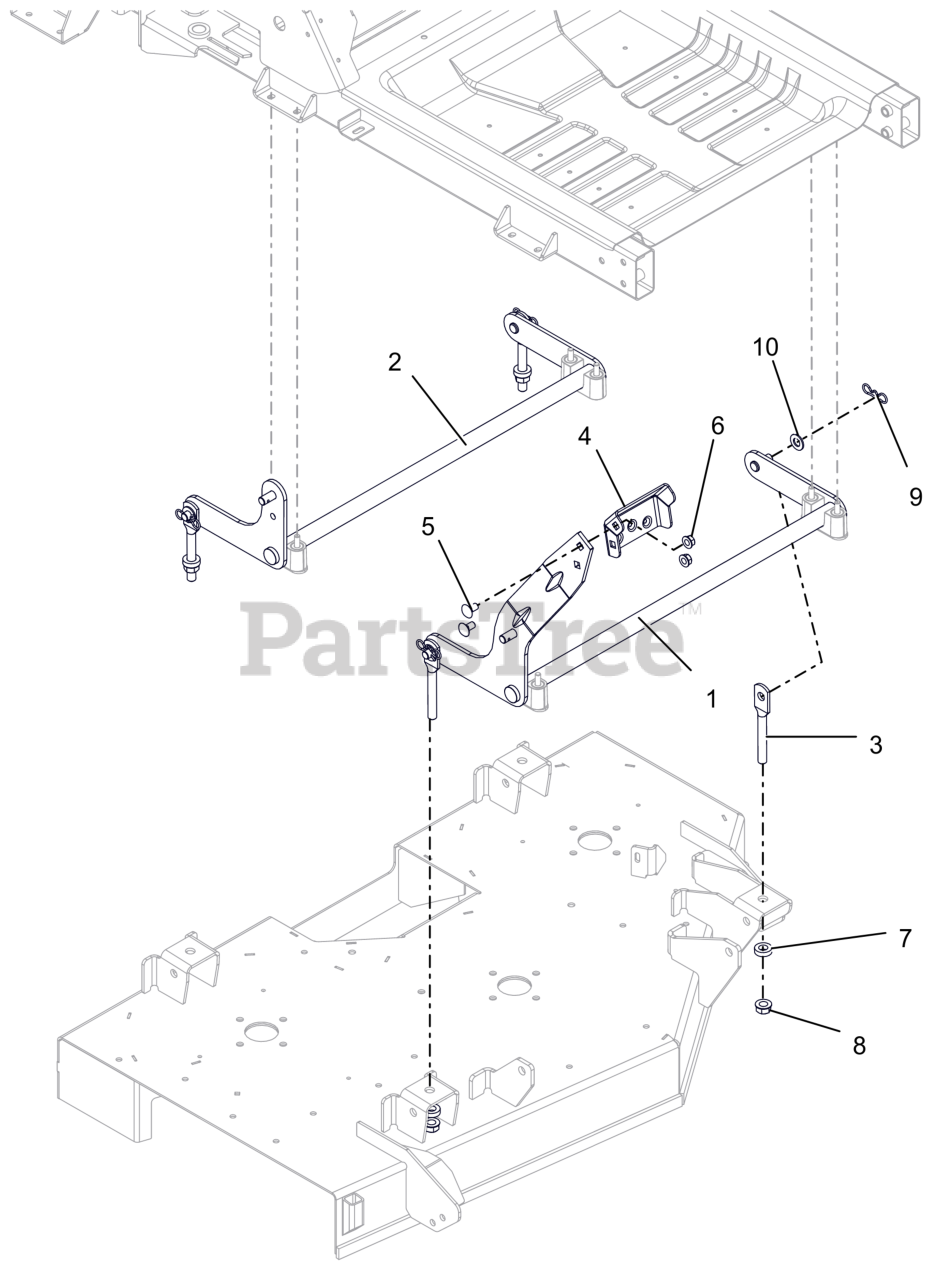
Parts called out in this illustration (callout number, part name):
1	WLDMT, FRONT DECK LIFT PIVOT
2	WLDMT, REAR DECK PIVOT
3	LINK,DECK (HOLE-LONG)
4	PEDAL, DECK LIFT (BOLT ON)
5	BLT,RHSN .38-16X.75 G5 BFP
6	NUT-LK-CTR-FLG .375-16 GF ZCC
7	WASHER, RUBBER
8	NUT-LK-CTR-FLG .500-13 GG ZCC
9	PIN, BOWTIE .091X1.875 ZCC
10	WSHR-FL-NYL .518X1.000X.080
